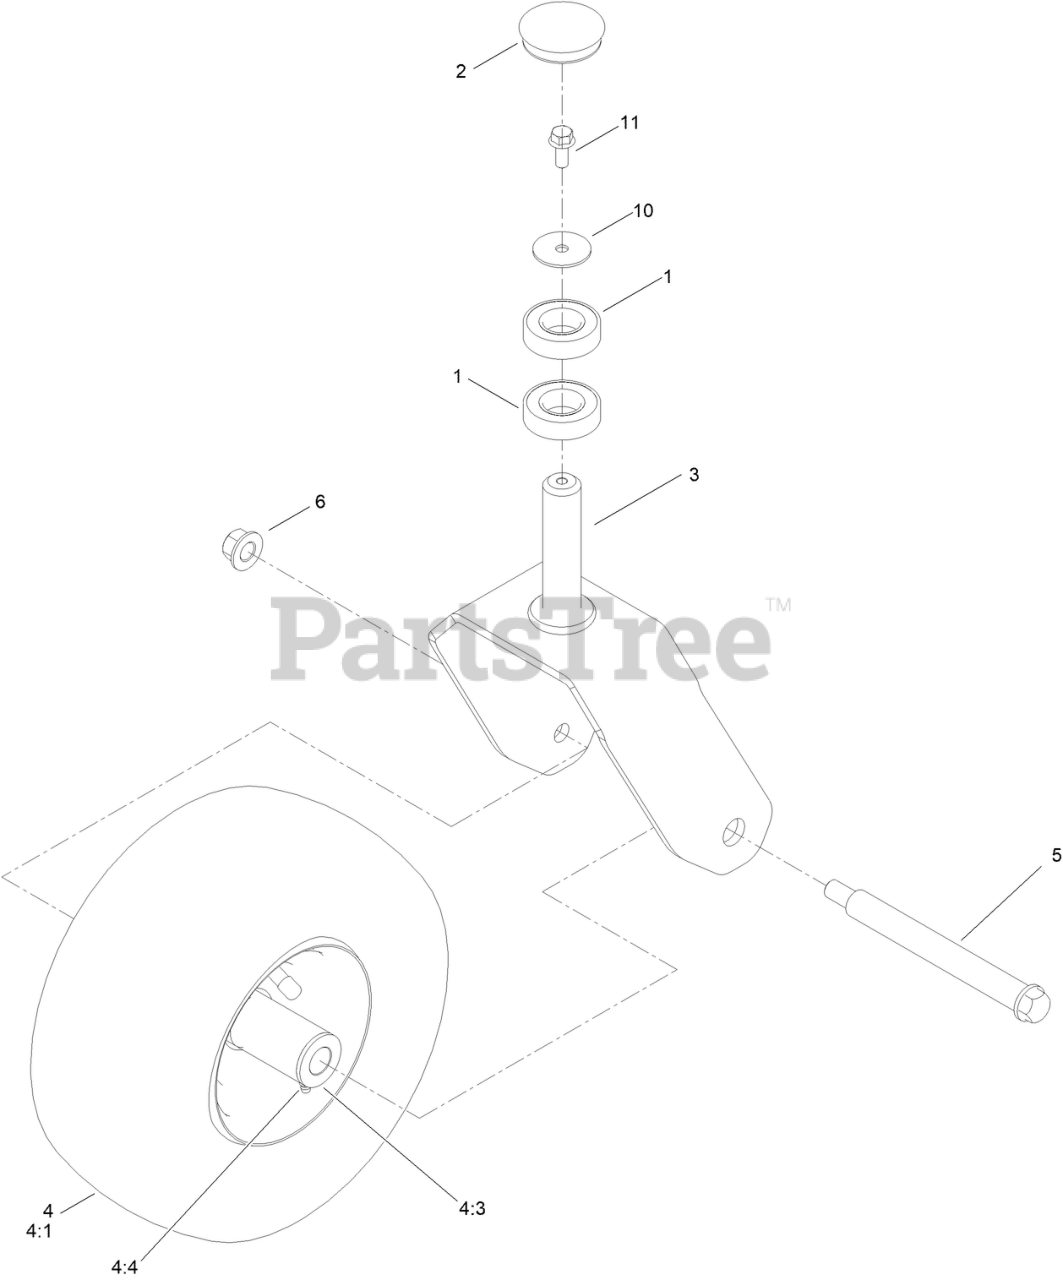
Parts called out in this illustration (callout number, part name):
1	BEARING-BALL
2	CAP,GREASE
3	FORK ASM [BLK-TXT]
4	WHEEL ASM - CASTER 12X6-5
4:1	TIRE 12X6-5
4:4	BUSHING-FLANGE
5	SCREW-SHOULDER HHF
6	NUT-LOCK
10	WASHER-FLAT
11	SCREW-HHF
